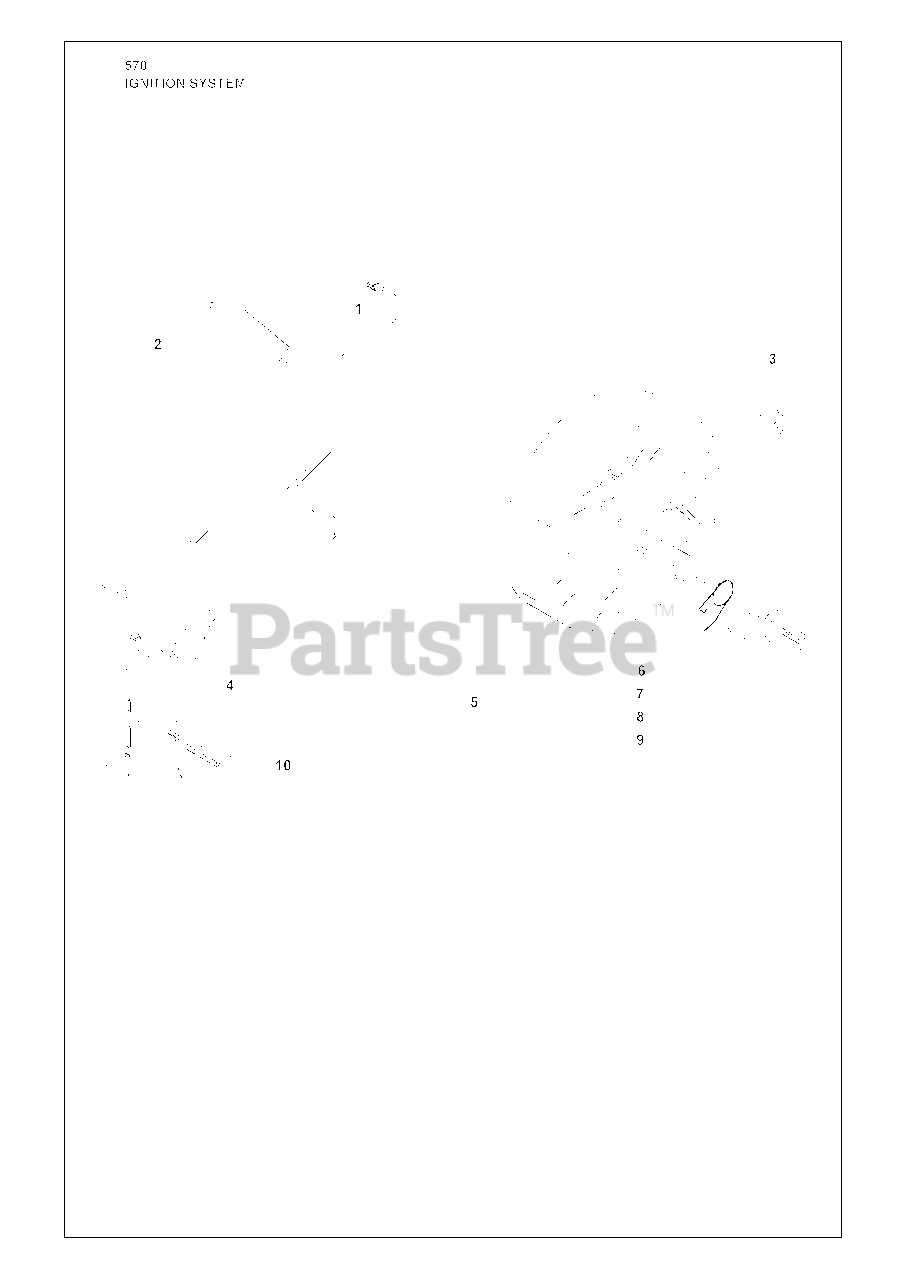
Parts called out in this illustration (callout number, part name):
1	SHORTING LEAD
2	SPARK PLUG CONN. KIT
3	NUT W/ WASHER
4	IGNITION MODULE
9	SCREW M5X14
